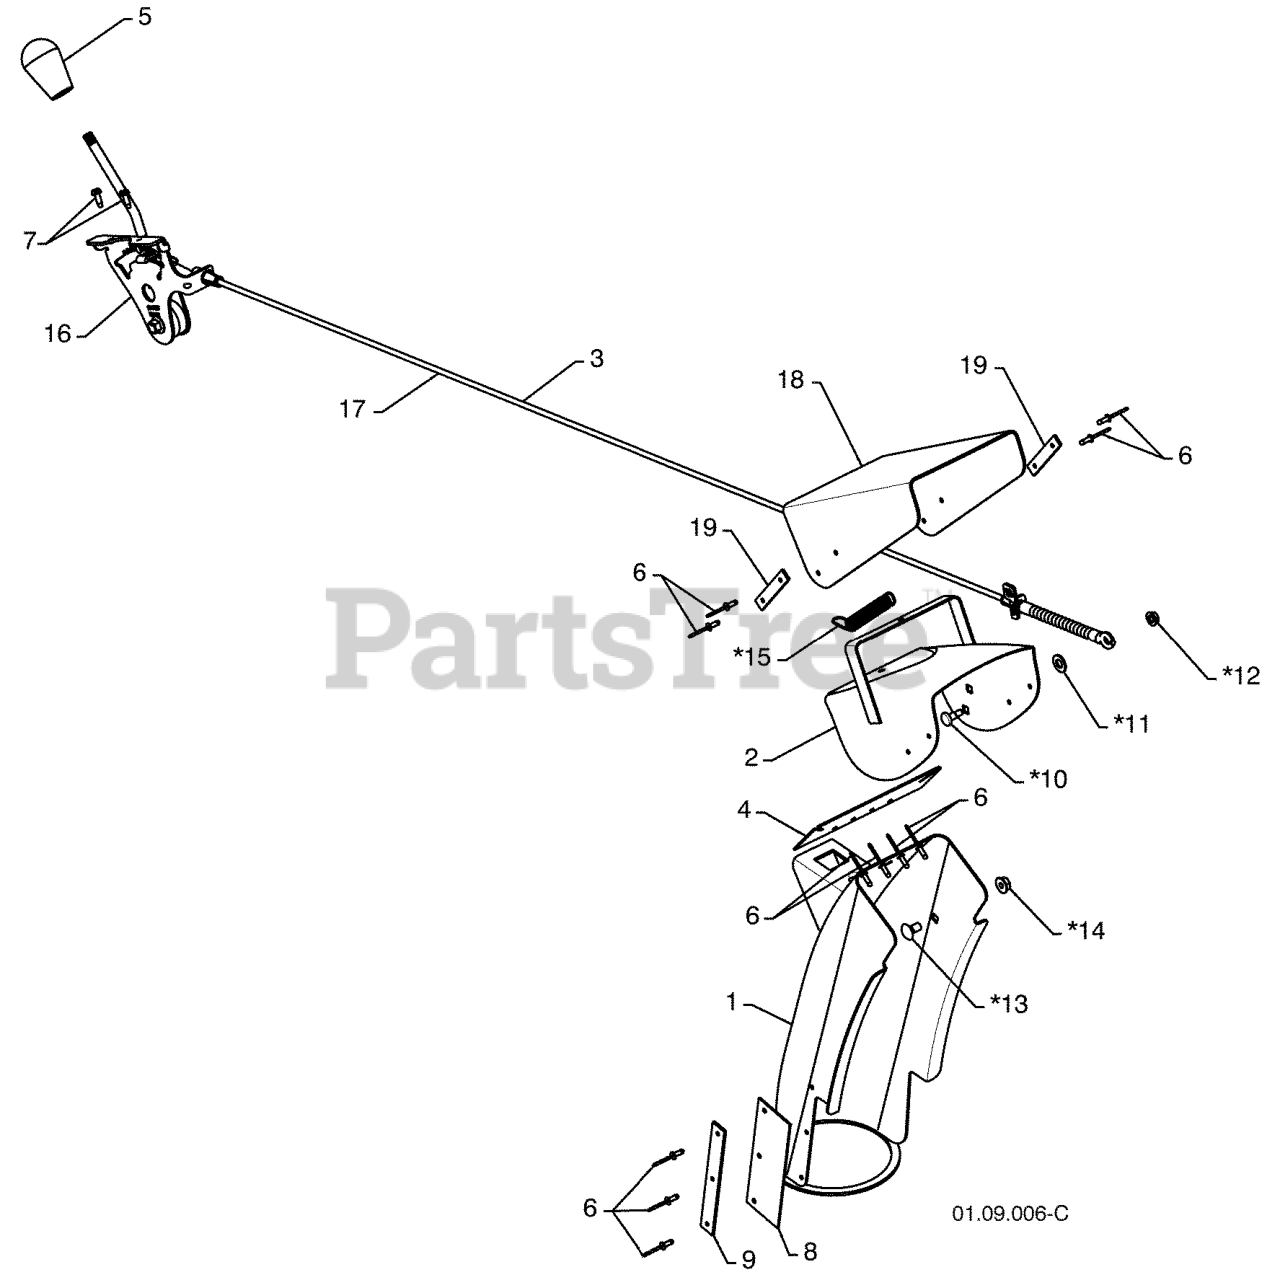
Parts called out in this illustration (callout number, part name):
1	CHUTE.WELDMENT
2	DEFLECTOR.WELDMENT.PNT.ORANGE
3	CONTROL.ASM.DEFLECTOR
4	SEAL.DEFLECTOR
5	KNOB LEVER, BLACK
6	RIVET BLIND
7	SCREW #10-24 X 5/8
8	SHIELD.SNOW.CHUTE
9	STRAP.SHEILD.RETAINER
10	BOLT, SHOULDER
11	WASHER, NYLON FRICTION
12	NUT.HEX.FLANGE.1/4
13	BOLT
14	NUT.LOCK.5/16-18
15	SPRING.DEFLECTOR.REM.CHUTE
16	RP CNTRL.HEAD.ASSEM.DEFLECTOR
17	SERVICE.CHUTE.DEF.CBL.GRY
18	SHIELD.DEFLECTOR.BLACK.SNOW
19	DEFLECTOR SHIELD STRAP
